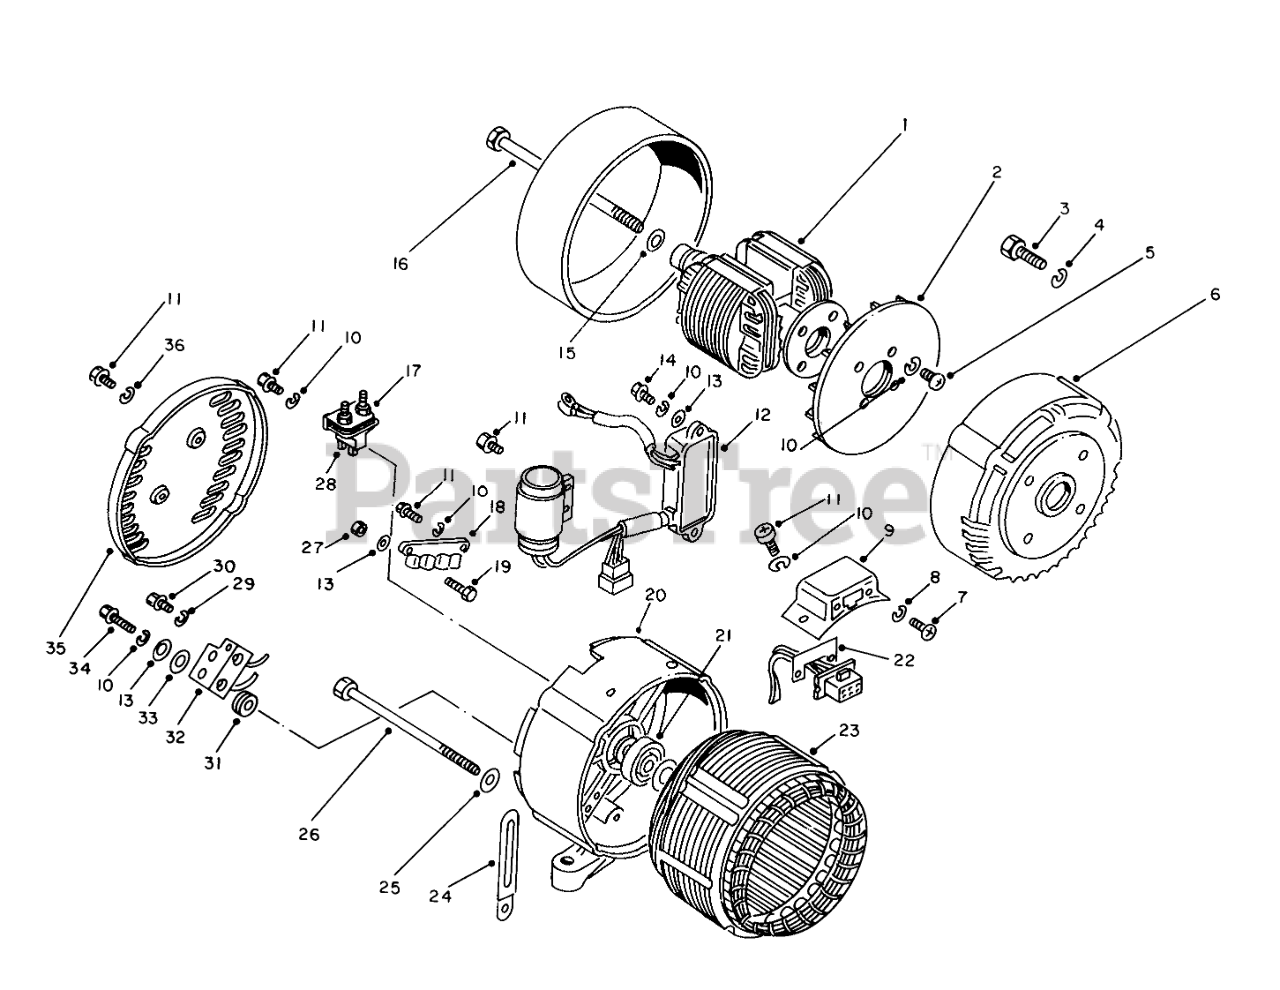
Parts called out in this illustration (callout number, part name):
1	Rotor
4	Lockwasher
5	Screw
6	Generator Assembly (Incl.Ref. #1, 2, 4, 10, 15, 16, 20, 21, &23)
7	SCREW
8	Lockwasher
9	COUPLER COVER
10	Washer
11	SCREW
12	Voltage Regulator
13	WASHER
14	Screw
15	Washer
17	Holder
18	Terminal
20	Rear Bracket
21	Bearing
22	Plate
24	Clamp
25	Washer
28	BRUSH
29	Lockwasher
31	Brush
32	DIODE
33	Washer
34	Screw
36	Washer
